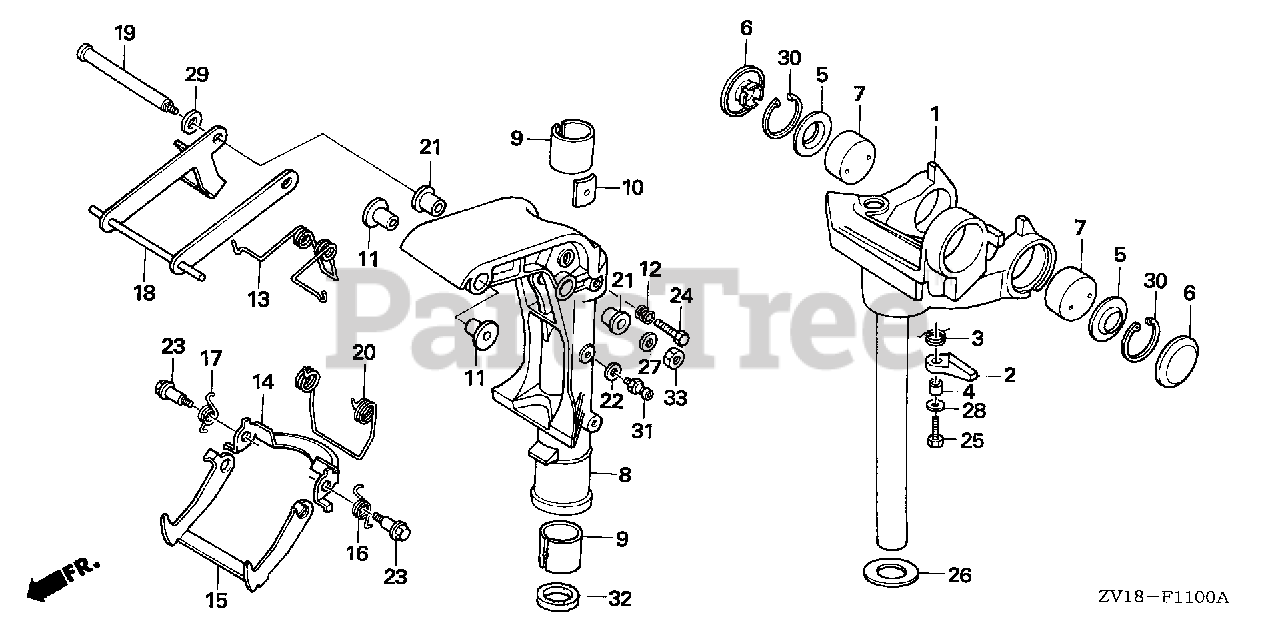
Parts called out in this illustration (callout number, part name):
1	FRAME, MOUNTING *NH282MU* (OYSTER SILVER METALLIC-U)
2	STOPPER, HANDLEBAR *NH282MU* (OYSTER SILVER METALLIC-U)
3	SPRING, HANDLE
4	COLLAR, STOPPER
5	WASHER, MOUNTING
6	CAP, MOUNTING
7	RUBBER, MOUNTING (UPPER)
8	CASE, SWIVEL *NH282MU* (OYSTER SILVER METALLIC-U)
9	LINER, SWIVEL CASE
10	BLOCK, FRICTION
11	BUSH, SWIVEL CASE
12	SPRING, FRICTION ADJUSTING
13	SPRING, HOOK RETURN
14	PLATE, REVERSE LOCK
15	HOOK, REVERSE LOCK
16	SPRING, L. REVERSE LOCK
17	SPRING, R. REVERSE LOCK
18	ARM, TILT
19	SHAFT, TILT
20	SPRING, REVERSE LOCK
21	BUSH, TILT LEVER
22	WASHER (6X11)
23	BOLT, REVERSE LOCK
24	BOLT, SPECIAL (8X20)
25	BOLT, HEX. (6X20)
26	WASHER, THRUST
27	WASHER, PLAIN (6MM)
28	WASHER, PLAIN (6MM)
30	CIRCLIP (INNER) (40)
31	NIPPLE, GREASE
32	OIL SEAL (27.8X33X5) (ARAI)
33	NUT, HEX. (6MM)
